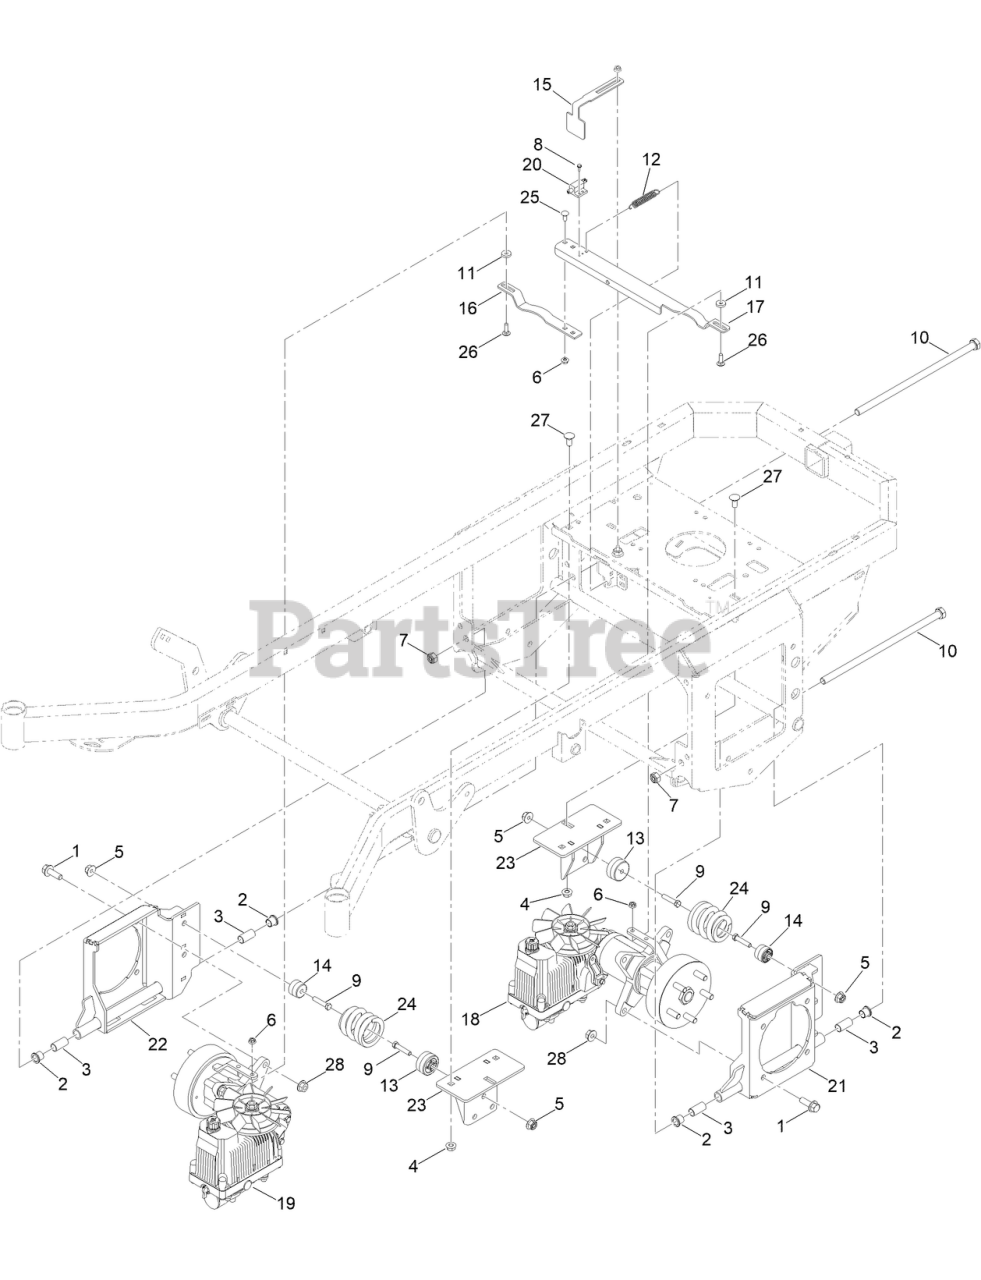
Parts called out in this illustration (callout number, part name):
1	SCREW-HHF
2	BUSHING-FLANGE
3	.625 ID X .750 OD X 1.500IN OI BUSHING
4	7/16-14 HEX FLANGE NUT W/SERR ZINC
5	3/8-16 NYLON INSERT FLANGE L/NUT YZ
6	5/16-18 NYLON INSERT FLANGE L/NUT ZC
7	5/8-11 NYLON INSERT FLANGE L/NUT ZINC
8	8-32 X 1/2 IND. HWH SLOT TYPE F TCS ZINC
9	3/8-16 X 1-3/4 HEX C/S GR 2 ZINC
10	5/8-11 X 15IN HEX C/S GR 2 ZC 3IN THD L
11	.312 ID X .875OD X .1875 THK F/W NYL
12	MWR BRAKE PEDAL RELEASE SPRING
13	SUSP SPRING INSIDE GUIDE
14	SUSP SPRING OUTSIDE GUIDE
15	STAND TRANS BRAKE INTERLOCK BRKT PAINT
16	MWR PARK BRAKE BRKT RT PAINT
17	MWR PARK BRAKE BRKT LT PAINT
18	HTJ12 PARKER LT SIDE HYDROSTATIC TRANSM
19	HTJ12 PARKER RT SIDE HYDROSTATIC TRANSM
20	NO PLUNGER LIMIT SWITCH
21	MWR LT RR SUSP ASSY-SRT-PRO HD
22	MWR RT RR SUSP ASSY-SRT-PRO HD PAINTED
23	MWR SUSP FRAME BRKT ASSY PAINT
24	SRT RR SUSP SPRING
25	BOLT-CARR
26	BOLT-CARR
27	SCREW-CARR
28	NUT-HHF
